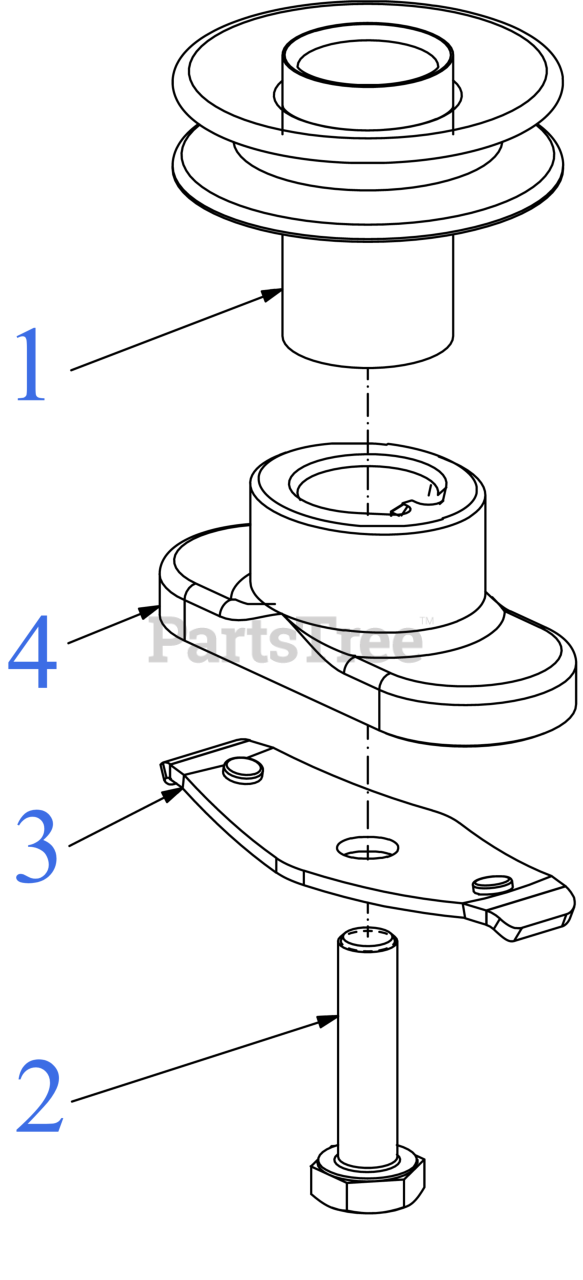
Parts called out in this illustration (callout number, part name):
1	ADAPTER (7/8 ID X .430)
2	SCREW 3/8-24 x 1.50 GR8
3	BLADE BELL SUPPORT
4	BLADE ADAPTER (#6 X 1.19 W/S)
